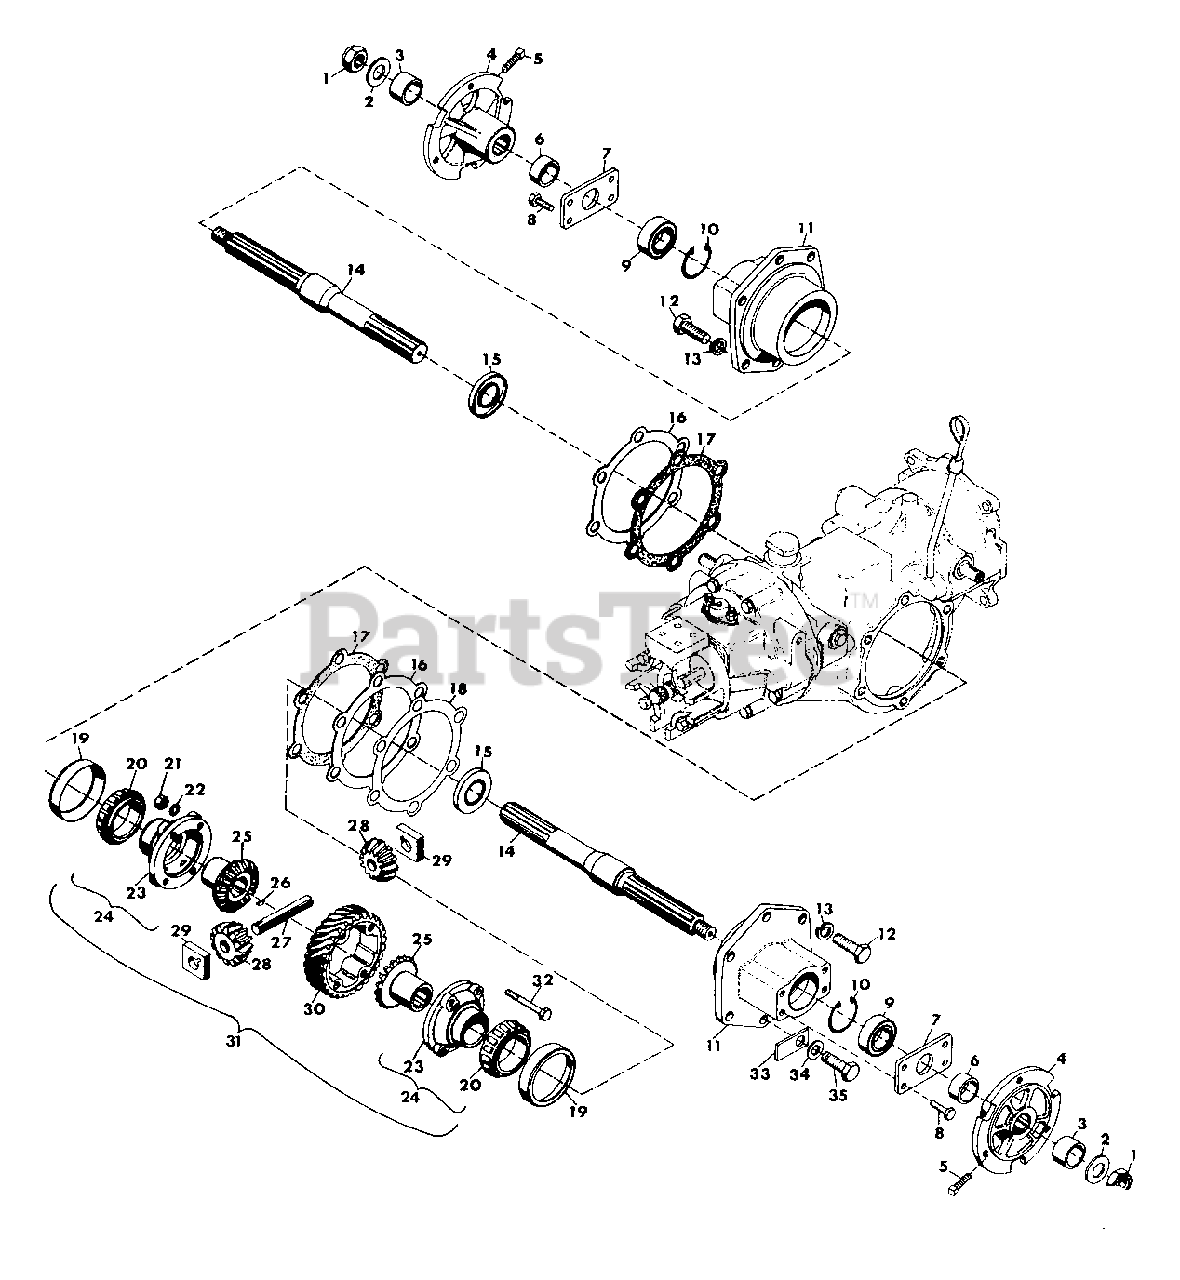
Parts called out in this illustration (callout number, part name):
1	Nut, Hex 3/4-10 Light Thin
2	Washer, Flat .812x1.469x.134
3	Spacer
4	Hub, Wheel
5	Screw, Set 7/16-14x1.00 SQHCP
6	Spacer
7	Plate, End
8	Bolt, Hex 3/8-16x.750
9	Bearing, Bail 1.000x2.000x.562
10	Ring, Retaining 2.000 Bore
11	Housing, Axle
12	Bolt, Hex 1/2-13x1
13	Washer, Lock 1/2 Reg.
14	Axle, Straight
15	Seal, Oil 1.188x2.000x.250
16	Shim, Axle Housing .005
17	Gasket, Axle Housing
18	Shim, Axle Housing .020
19	Cup, Roller Bearing
20	Cone, Roller Bearing
21	Nut, Hex 5/16-24
22	Washer, Lock 5/16 Int. Tooth
23	Housing, Differential
24	Assembly, Differential Housing
25	Gear, Differential Bevel
26	Key, Woodruff .125x.375 Hard
27	Pin, Spider Pinion
28	Gear, Spider Bevel
29	Block, Drive
30	Gear, 6 Lead Worm
31	Assembly, Diff. Std. 6 Lead
32	Bolt, Hex 5/16-24x2.75
33	Washer, Oil Drain
34	Washer, Flat .531x1.062x.095
35	Bolt, Hex 1/2-13x1 Nylon Insert
